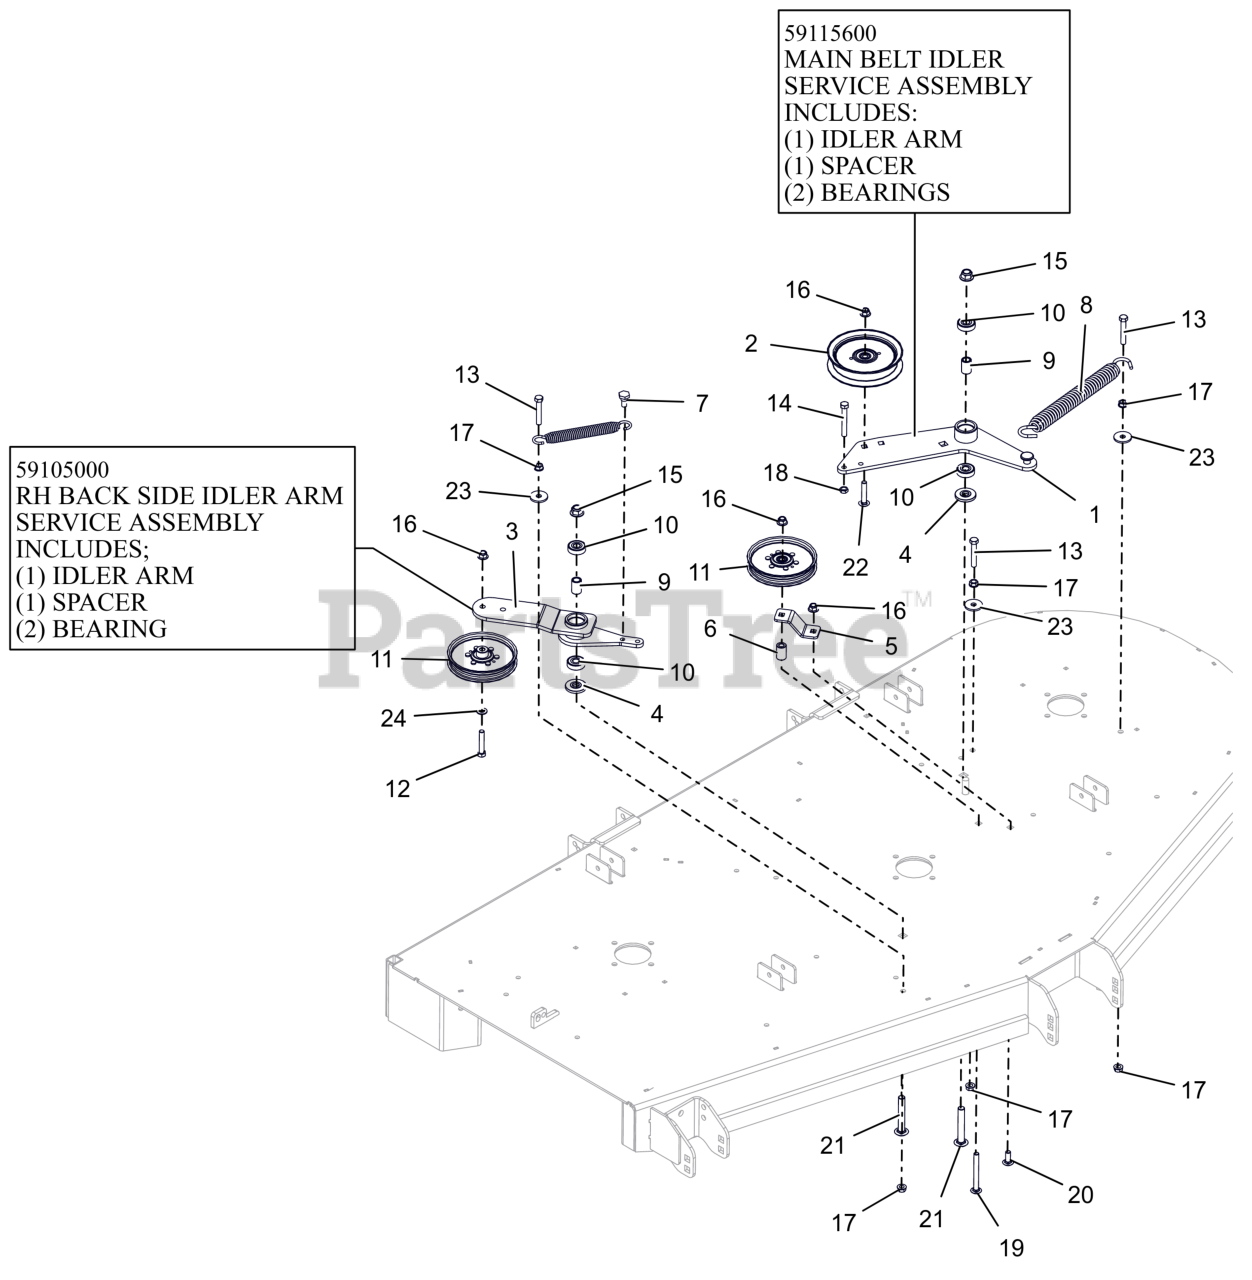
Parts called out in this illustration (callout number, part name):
1	WLDMT, DECK PTO IDLR ARM
1	ASSEMBLY, MAIN BELT IDLER
2	IDLER, FLAT 5.00"
3	WLDMT, DECK RH IDLER ARM
3	RH BACKSIDE IDLER ARM ASSEMBLY
4	SPACER, IDLER ARM
5	PTO FIXED IDLER MTG BRKT -RED
6	BUSHING, SLV .380X.750X1.190
7	BLT,SHLDR EP .38-16X.30 HEX YZ
8	SPRING, EXTENSION
9	SPACER .510 X .75 X 1.1485
10	BRG-BALL .500X1.38X.437
11	PULLEY, FLAT IDLER
12	BLT,HEX .38-16X2.00 G5 ZCC
13	BLT,HEX .38-16X2.25 G5 ZCC
14	BLT, HEX .38-16X2.75 G5 ZCC
15	NUT,NYL-FLG .50-13 GF ZCC
16	NUT,NYL-FLG .38-16 GF ZCC
17	NUT, SPNLK-FLG .38-16 G5 ZCC
18	NUT-JAM .375-16 G2 ZCC
19	BLT,RHSSN .38-16X3.50 G5 ZCC
20	BLT,RHSSN .38-16X1.00 G5 ZCC
21	BTL,RHSSN .500-13 X 3.25 G5 ZCC
22	BLT,RHSSN.375-16X2.00 G5 ZCC
23	WSHR,FLT .406X1.375X.135 ZCC
24	WSHR,FLT .406X.812X.065 ZCC
